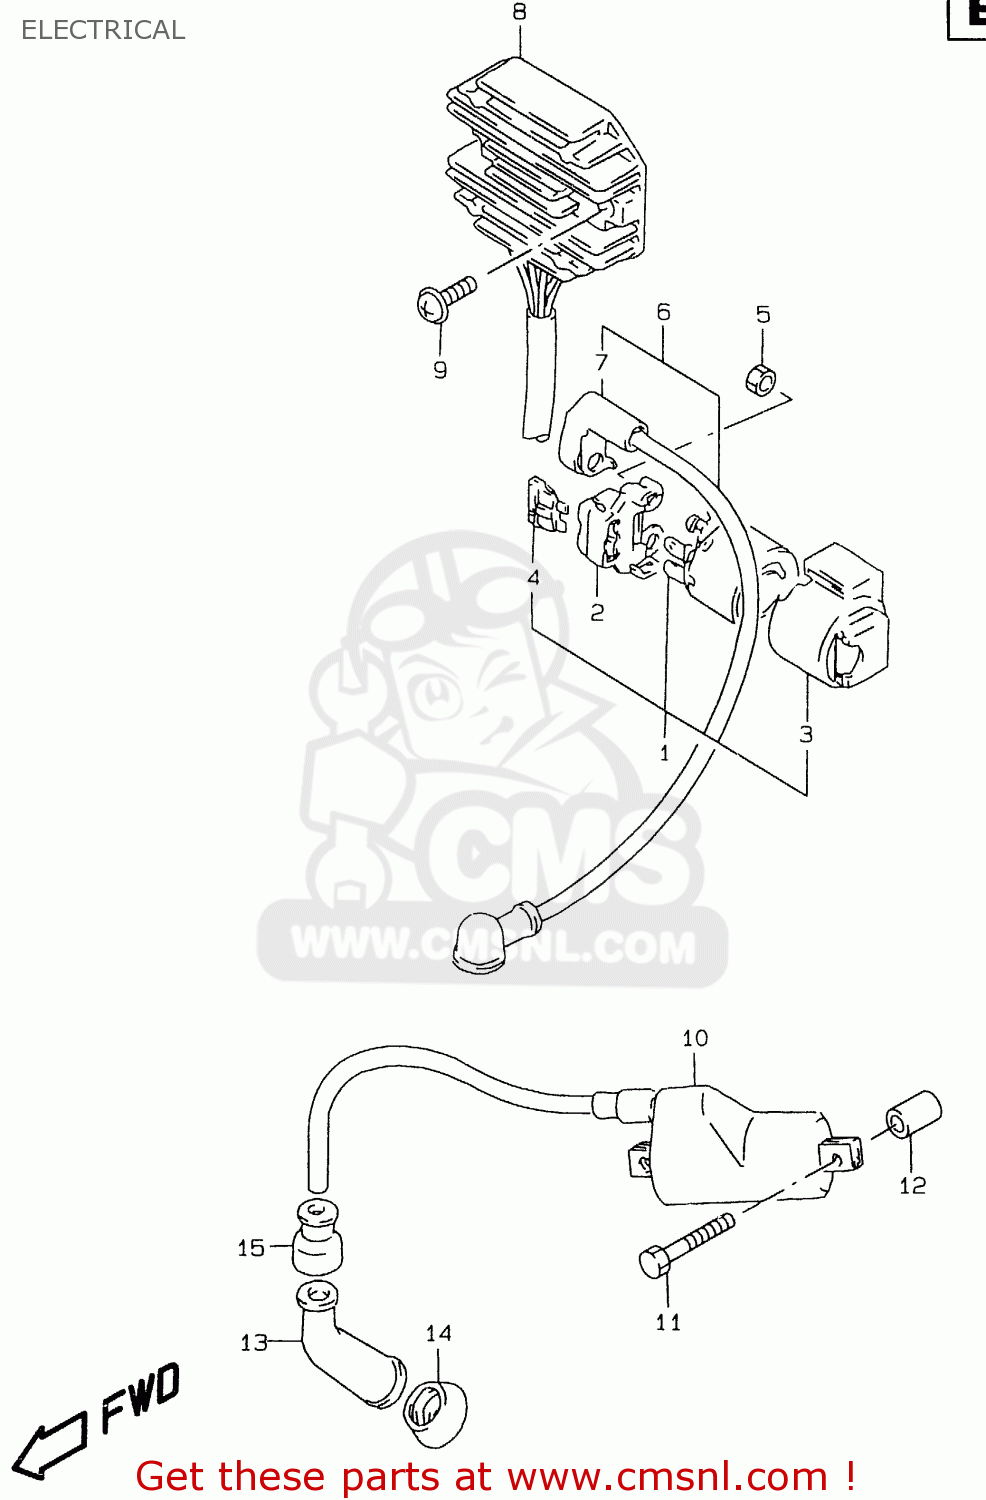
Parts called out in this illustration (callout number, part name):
1	RELAY ASSY,STARTING MOTOR
2	TERMINAL,RELAY
3	BRACKET,STARTING MOTOR RELAY
4	FUSE(20A)
5	NUT
6	WIRE,STARTER MOTOR LEAD
7	CAP,STARTER RELAY TERMINAL
8	RECTIFIER ASSEMBLY
9	SCREW
10	COIL ASSY,IGNITION
11	BOLT
12	SPACER(6.2X12X18)
13	CAP ASSY,SPARK PLUG
14	SEAL,SPARK PLUG CAP
15	SEAL,HIGH TENSION CORD
